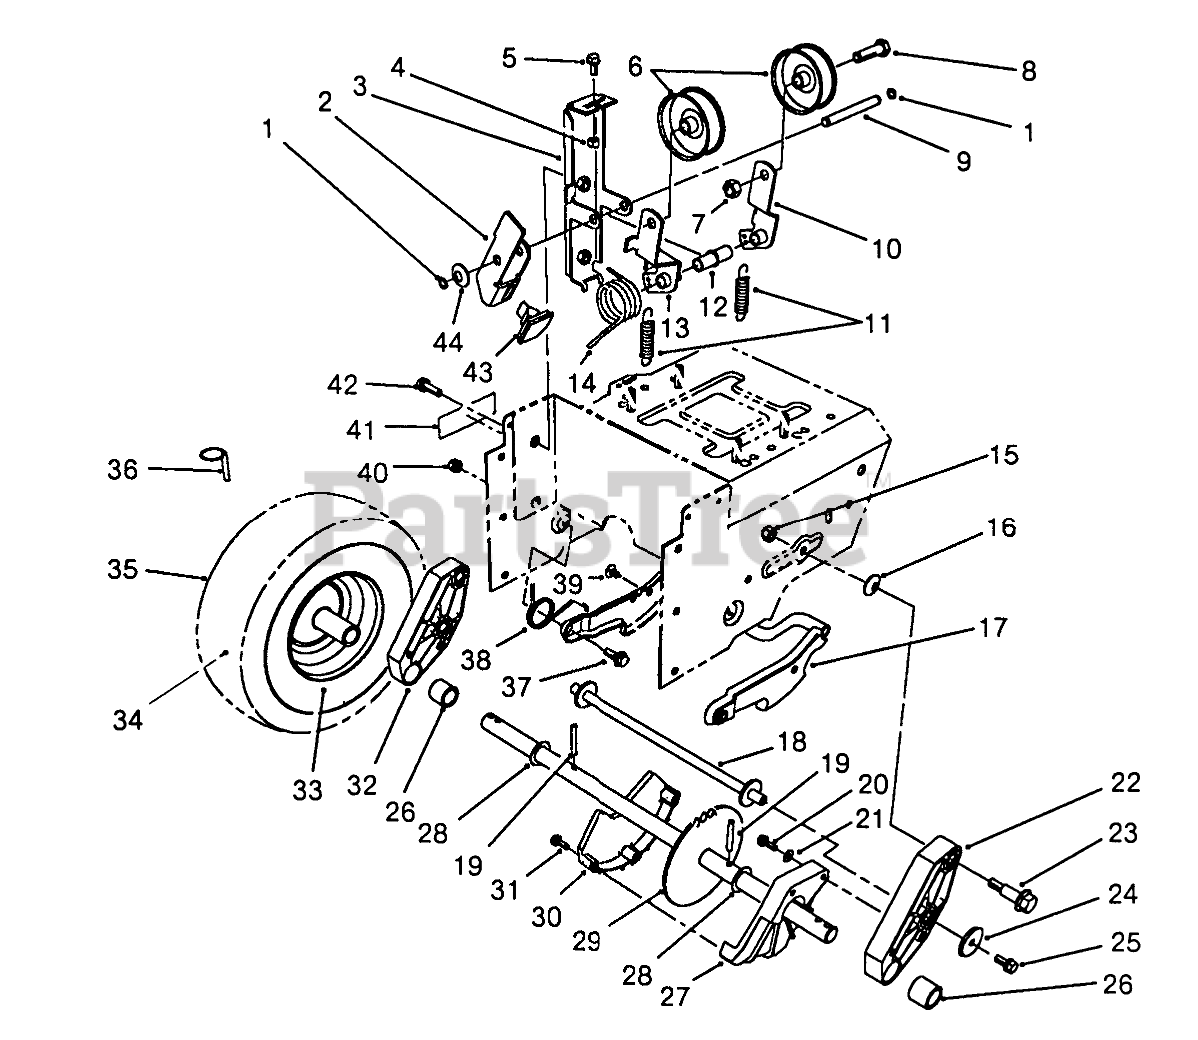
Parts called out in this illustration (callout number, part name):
1	RING-RETAINING
2	ARM-BRAKE
3	IDLER ARM BRACKET ASM
4	NUT-LOCK, NI
5	SCREW-HHF
6	PULLEY-IDLER
7	NUT-LOCK, NI
8	SCREW-HH
9	PIN-IDLER
10	ARM-IDLER, TRACTION
11	SPRING-EXTENSION
12	BUSHING-IDLER
13	ARM-IDLER, IMPELLER
14	TORSION SPRING
15	NUT-LOCK, NI
16	WASHER-SPRING
17	Latch-Arm
18	PIVOT TUBE WA
19	PIN-ROLL, SLOTTED
20	SCREW-HWH
21	WASHER-FLAT
22	Pivot Arm Assembly L.H (Incl.Ref. #26)
23	BOLT-SHOULDER
24	WASHER
25	SCREW-TAPTITE
26	BUSHING-AXLE
27	GUARD-CHAIN, LH
28	WASHER-THRUST
30	GUARD-CHAIN, RH
32	Pivot Arm Assembly R.H.(Incl.Ref. #26)
33	WHEEL RIM
34	INNER TUBE
36	PIN-LYNCH
37	SCREW-SHOULDER
38	SPRING-LATCH, TORSION
39	FASTENER-PANEL
40	NUT-LOCK, NI
41	Decal-Warning
42	SCREW-HHF
43	Brake Pad
44	WASHER-CURVED
